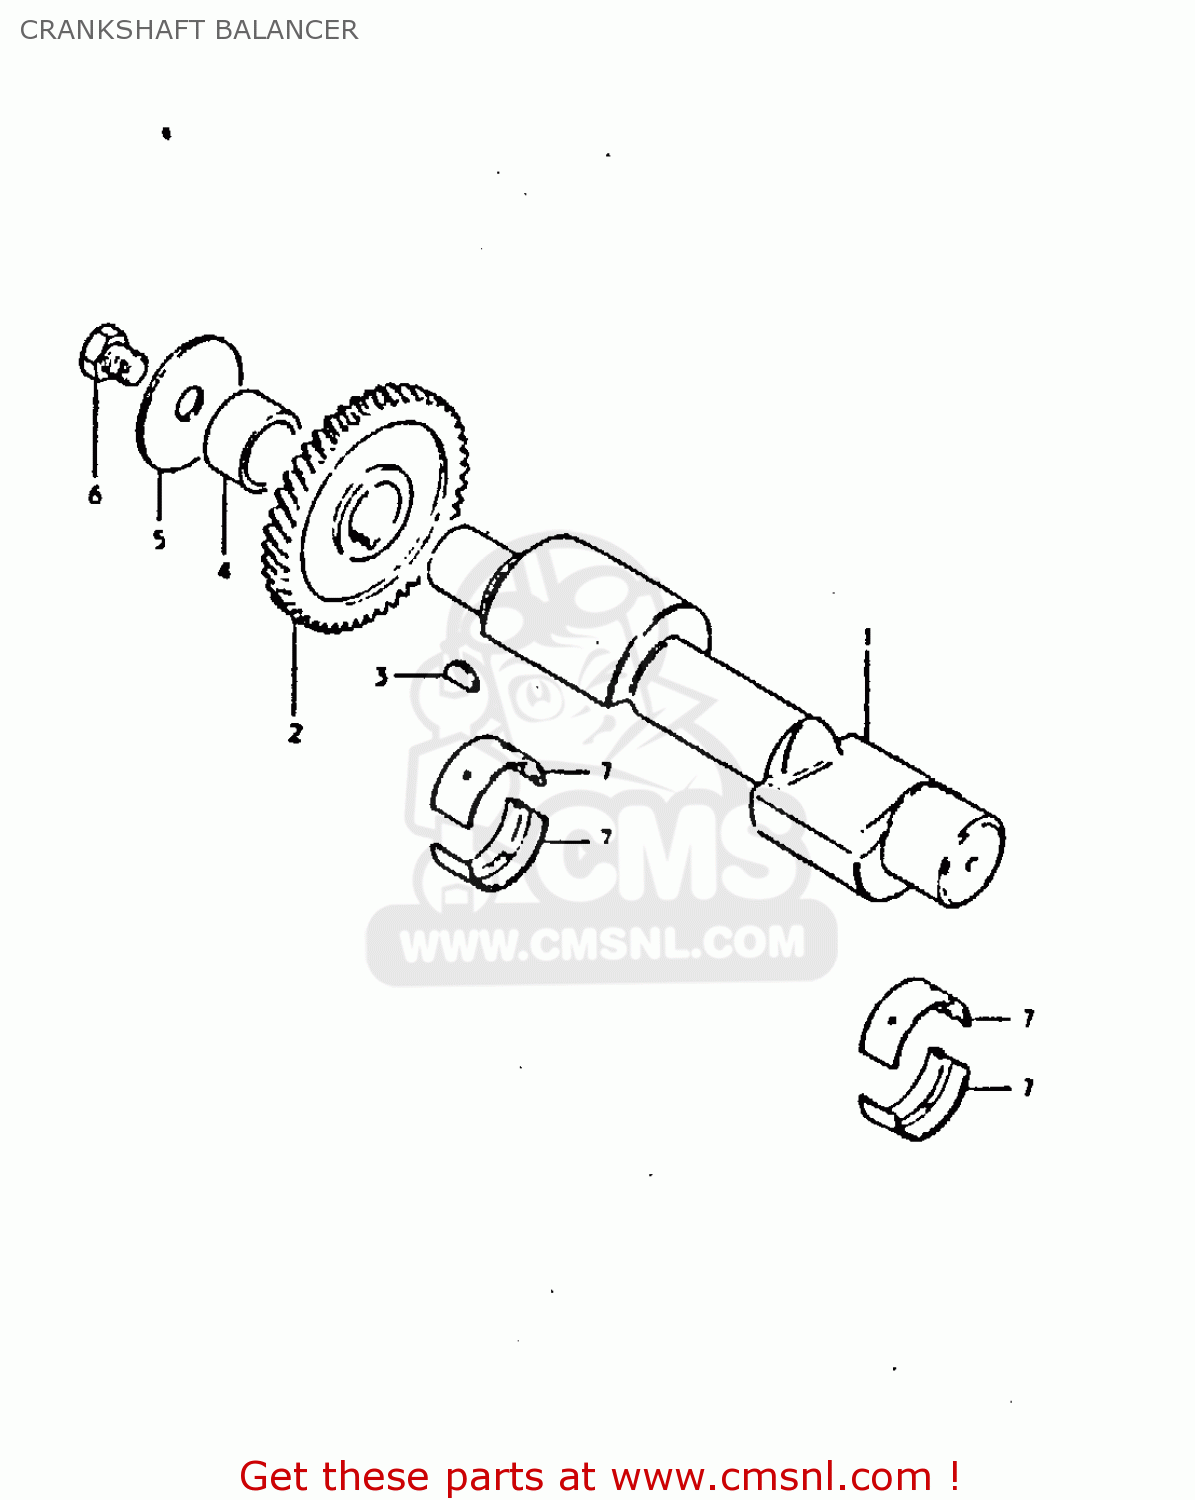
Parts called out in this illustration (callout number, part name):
1	BALANCER,CRANKSHAFT
2	GEAR,CRANK BALANCER
3	KEY 4MM
4	SPACER
5	WASHER(12X50X3)
6	BOLT
7	METAL CRANKSHAFT (BROWN)
